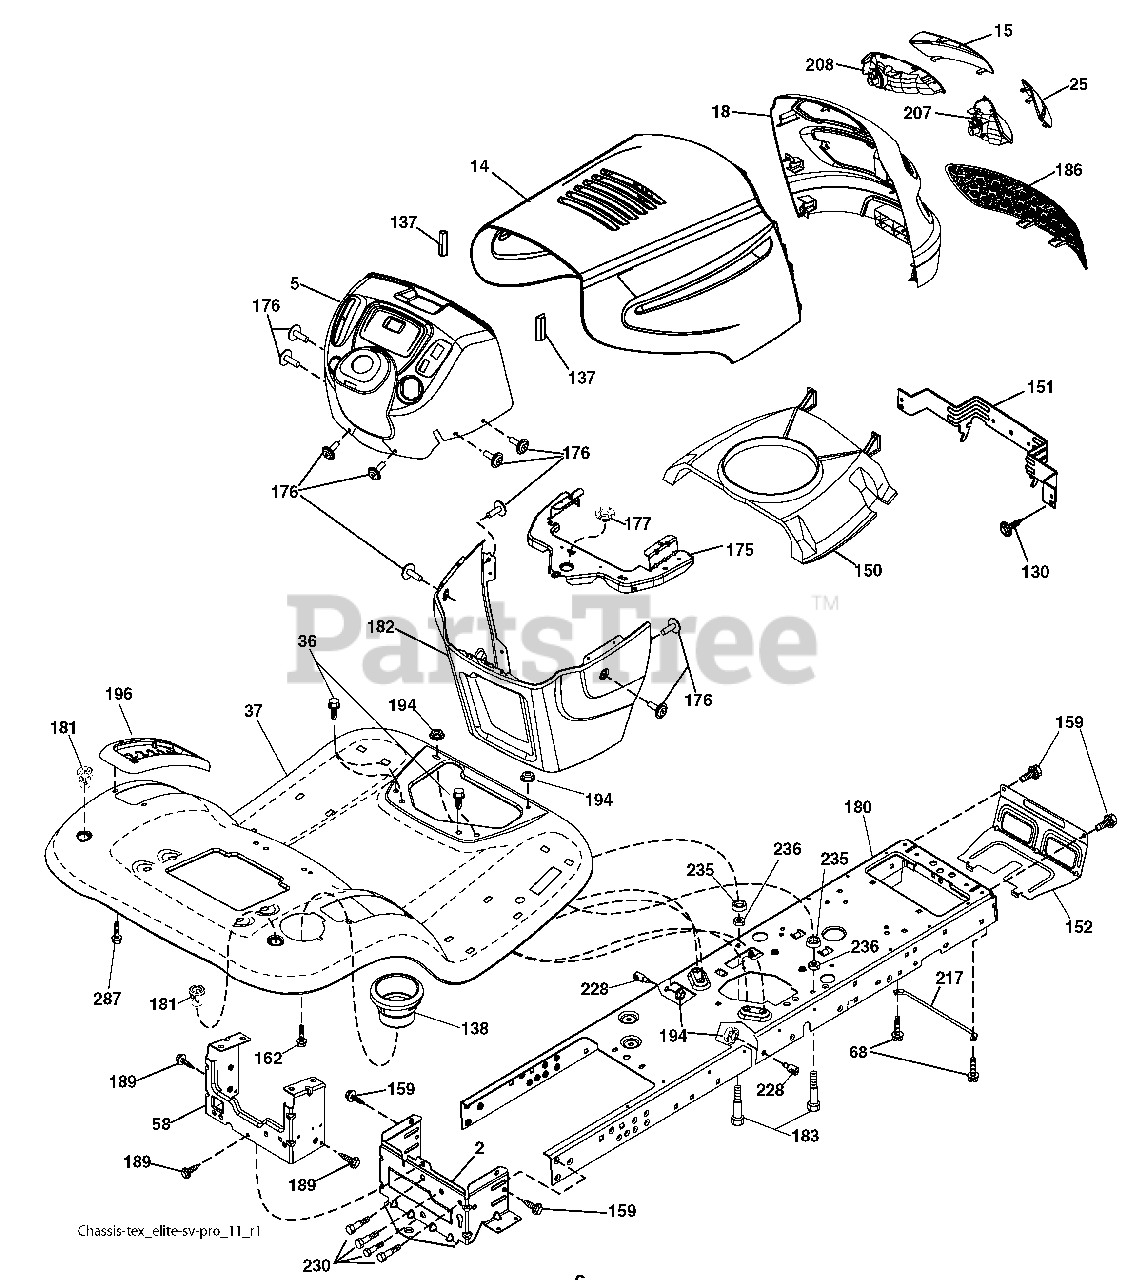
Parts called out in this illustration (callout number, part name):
2	Drawbar Lower
5	Dash
14	Hood
15	Lens Grille LH
18	Grille
25	Lens Grille RH
36	Screw 5/16-18 x 3/4
37	Fender
58	Drawbar Upper
68	Screw Thdrol 5/16-18 x 1/2
130	Screw #10 x 0.750 BOS Thread
137	Bumper Hood
138	Cupholder
150	Duct Heat Hood
151	Bracket Pivot
152	Shield Browning/Debris
159	Screw Hexwsh Thdrol 3/8-16 x 3/4
162	Screw Hex Wsh Hi-Lo 1/4 x 1/2
175	Crossmember
176	Screw 10-24 x 5/8 Wshd Qdrx
177	Bushing Steering
181	Bushing Mtg. Fender Crgo.
182	Dash Lower
183	Bolt Fin Hex 5/16-18 x 1-1/4
189	Screw 5/16-18 x 3/4
194	Nut Lock Hex Flange 5/16-18
196	Console Asm. Deck Lift
207	Bezel Grille RH
208	Bezel Grille LH
217	Rod Pivot Chassis
228	Stud Fastener
230	Bolt Shoulder 5/16-18
235	Spacer Fender
236	Nut center Lock 5/16-18
287	Screw Hex Washead 1/4-20 x 3/8
